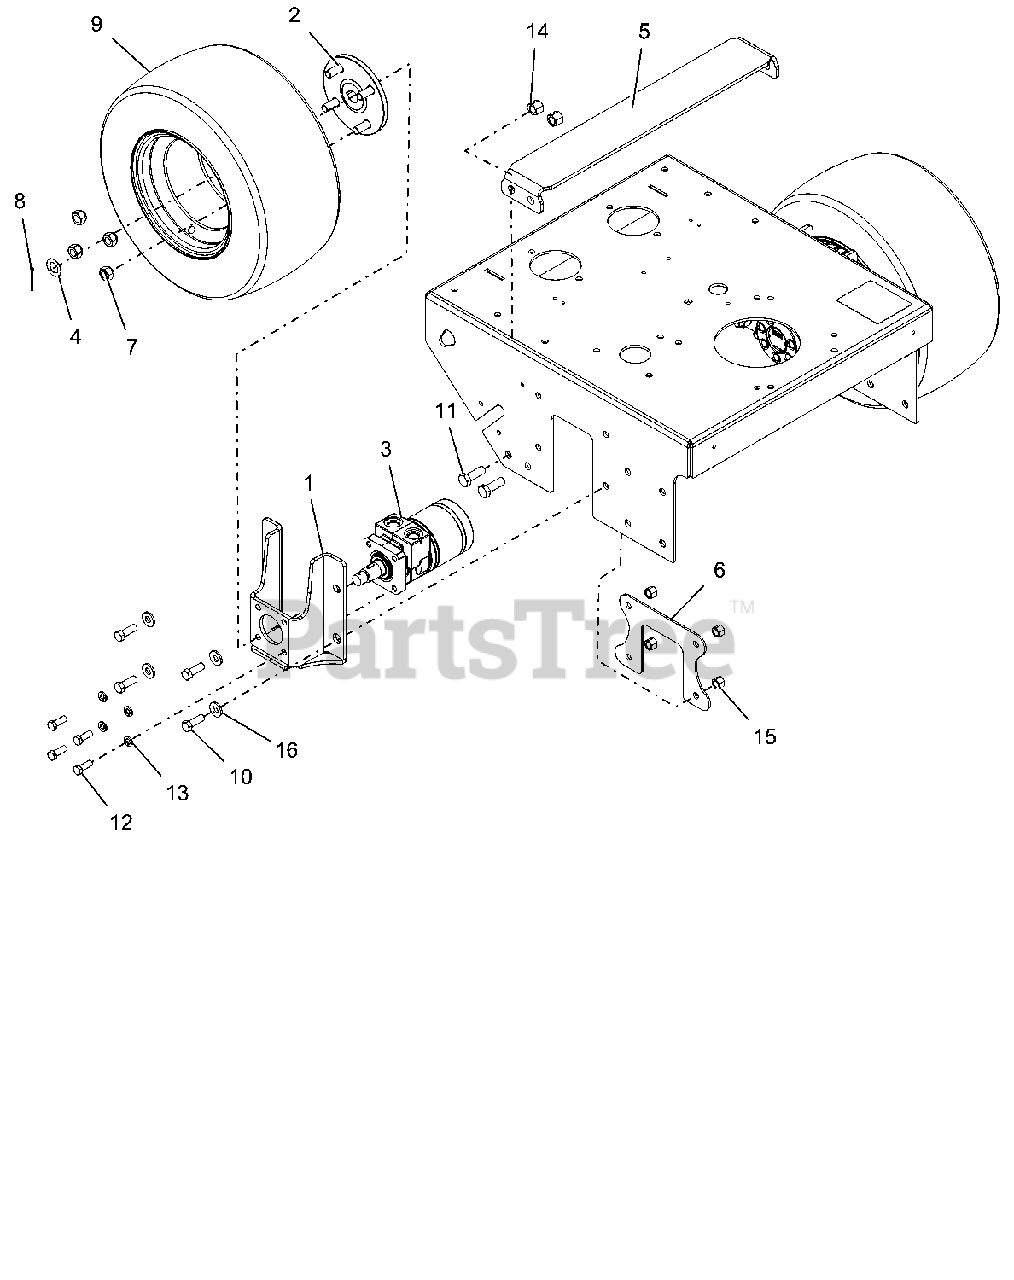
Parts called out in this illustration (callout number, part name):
1	WLDMT, WHEEL MOTOR BRACKET-RED
2	ASSY, WHEEL HUB
3	MOTOR, HYDRAULIC WHEEL
4	BUSHING, MACH .75 X 1.25 X .048
5	PLATE, ENGINE BED REAR 52/48-RED
6	PLATE, ENGINE BED DOUBLE-RED
7	NUT, 1/2-20 LUG C
8	PIN, COTTER
9	ASSM, WHL/TIRE 16X7.50-8 K500
10	BLT-HEX .44-14X1.25 GR5 YWZC
11	BLT-HEX .50-13X1.50 GR5 YWZC
12	BOLT, 3/8-16 X 1 GR8 BLACK
13	WSHR-LK .38X.094 REG YWZC
14	NUT-LK-NYL .50-13 YWZC
15	NUT-LK-NYL .44-14 YWZC
16	WSHR-FL-STL .468X1.00X.125 YWZC
